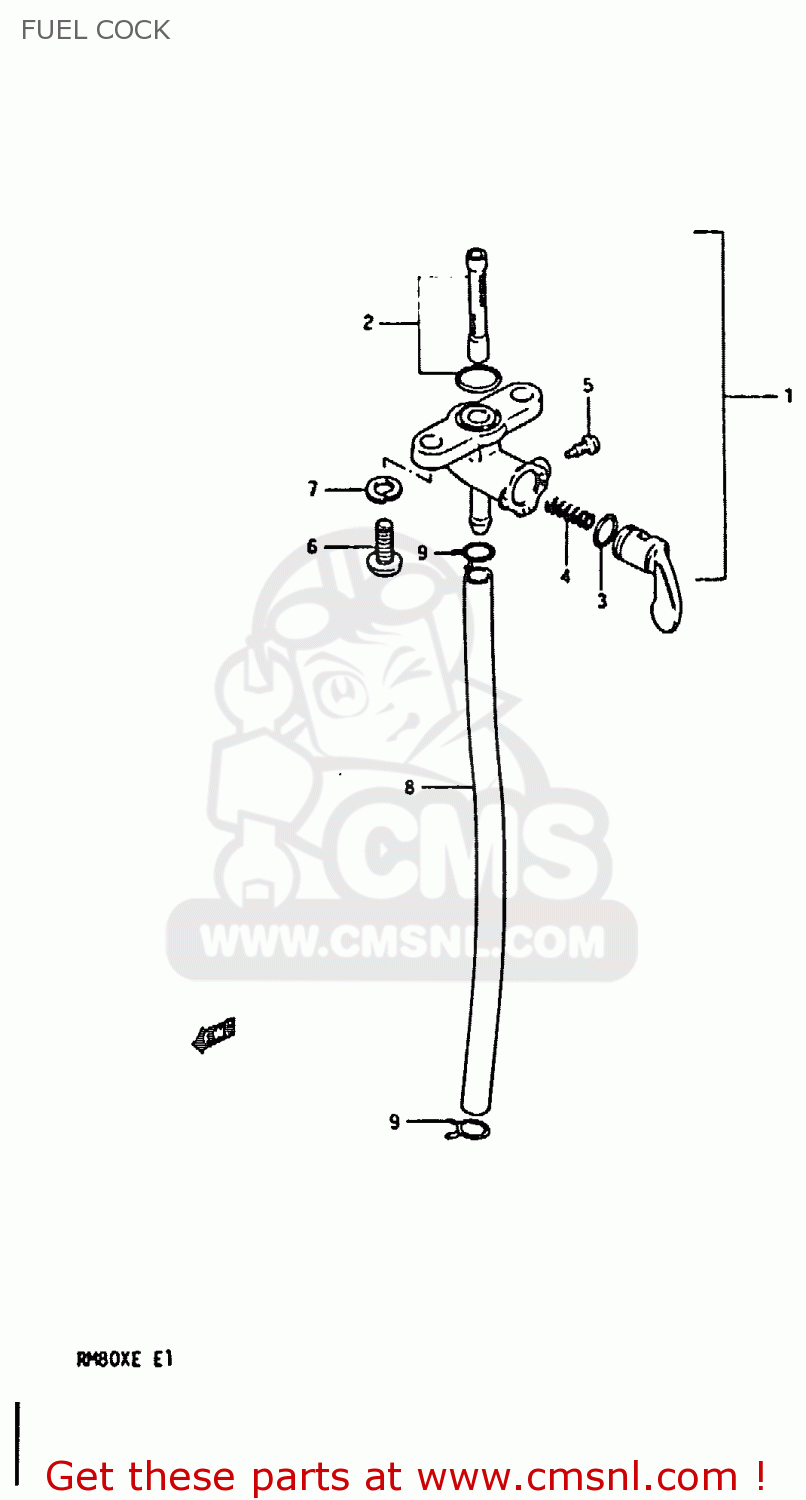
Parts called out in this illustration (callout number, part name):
1	COCK ASSY,FUEL
2	FILTER SET FUEL
3	O RING,LEVER
4	SPRING,FUEL COCK VALUE
5	SCREW
6	SCREW
7	LOCK WASHER
8	HOSE
9	CLIP
